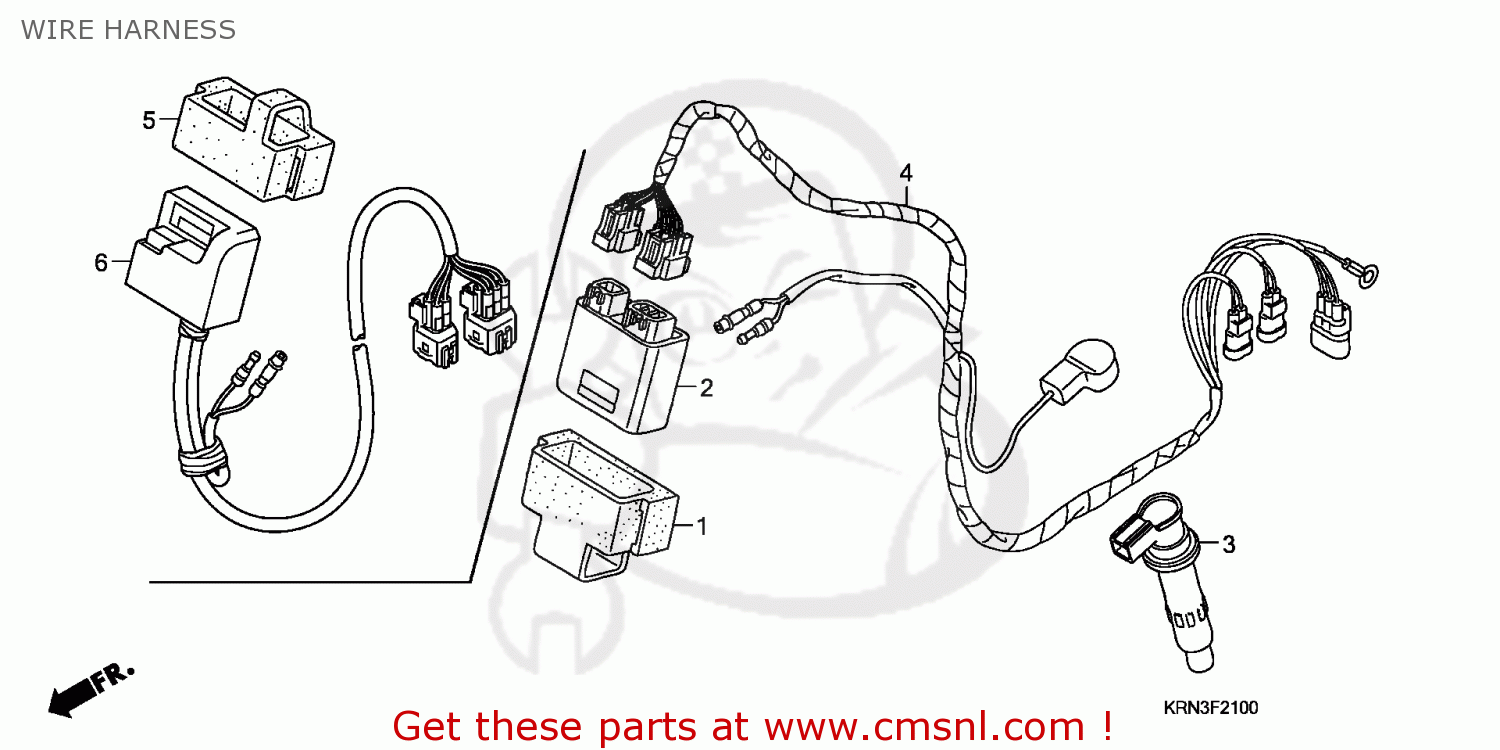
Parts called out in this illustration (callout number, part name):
3	CAP&COIL,IGN(CDI)
4	HARNESS WIRE
5	CUSHION,CDI UNIT
6	UNIT COMP,CDI
